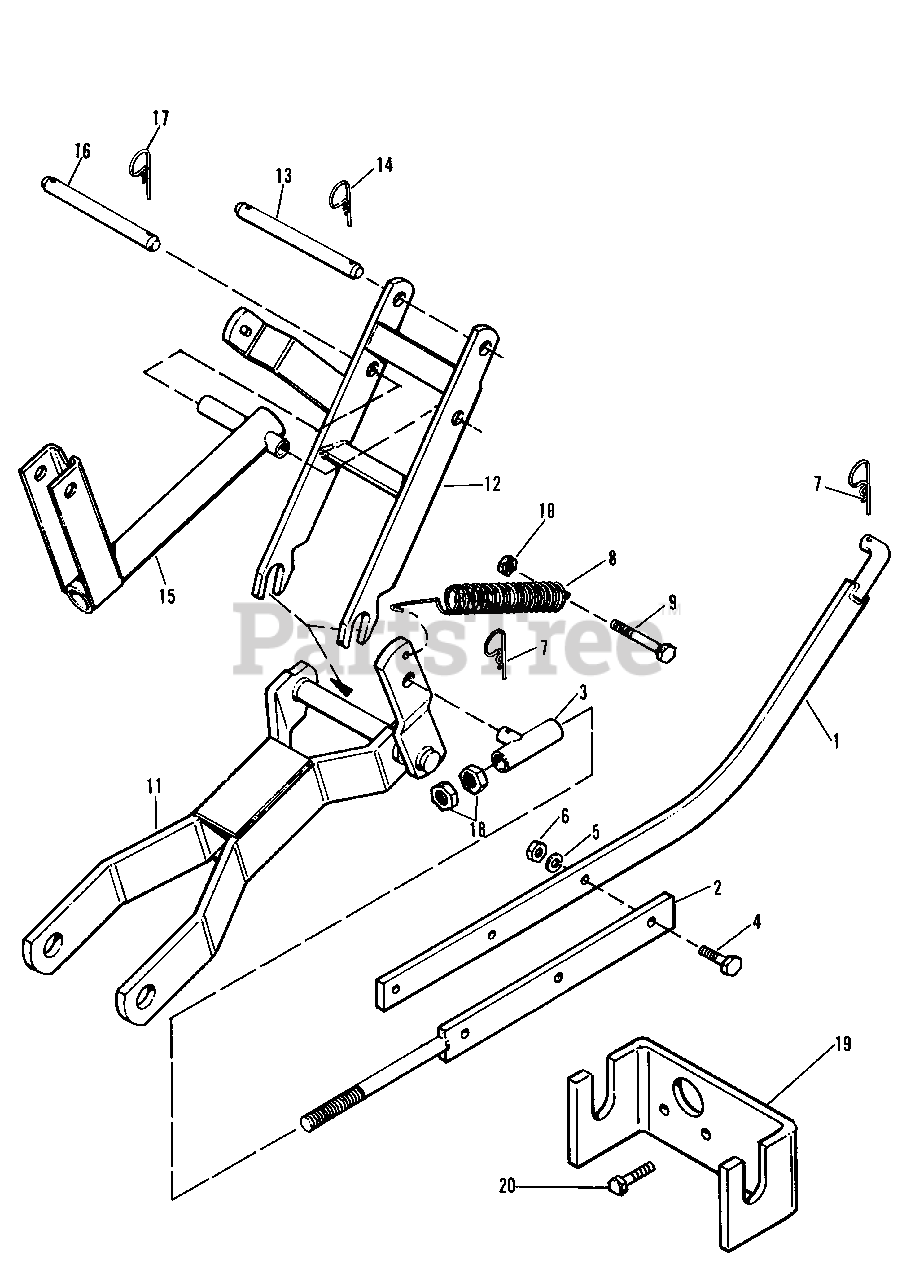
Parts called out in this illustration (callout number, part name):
1	Lift Arm Assembly (Front)
2	Lift Arm Assembly (Rear)
3	Guide Tube Assembly
4	Hex Capscrew, 3/8"-16 x 1-1/4" lg.
5	Lock Washer, 3/8"
6	Hex Nut, Full, 3/8"-16
7	Spring Clips
9	Hex Capscrew, 3/8"-16 x 2-1/2" lg.
10	Hex Nut, Full, 3/8"-16
11	Hitch & Lift Assembly
12	Strut Assembly
14	Spring Clips
17	Spring Clips
18	Hex Nuts, Full, Tinnerman
19	Attachment Hitch
20	Hex Capscrew, 3/8"-16 x 1-1/4" lg.
